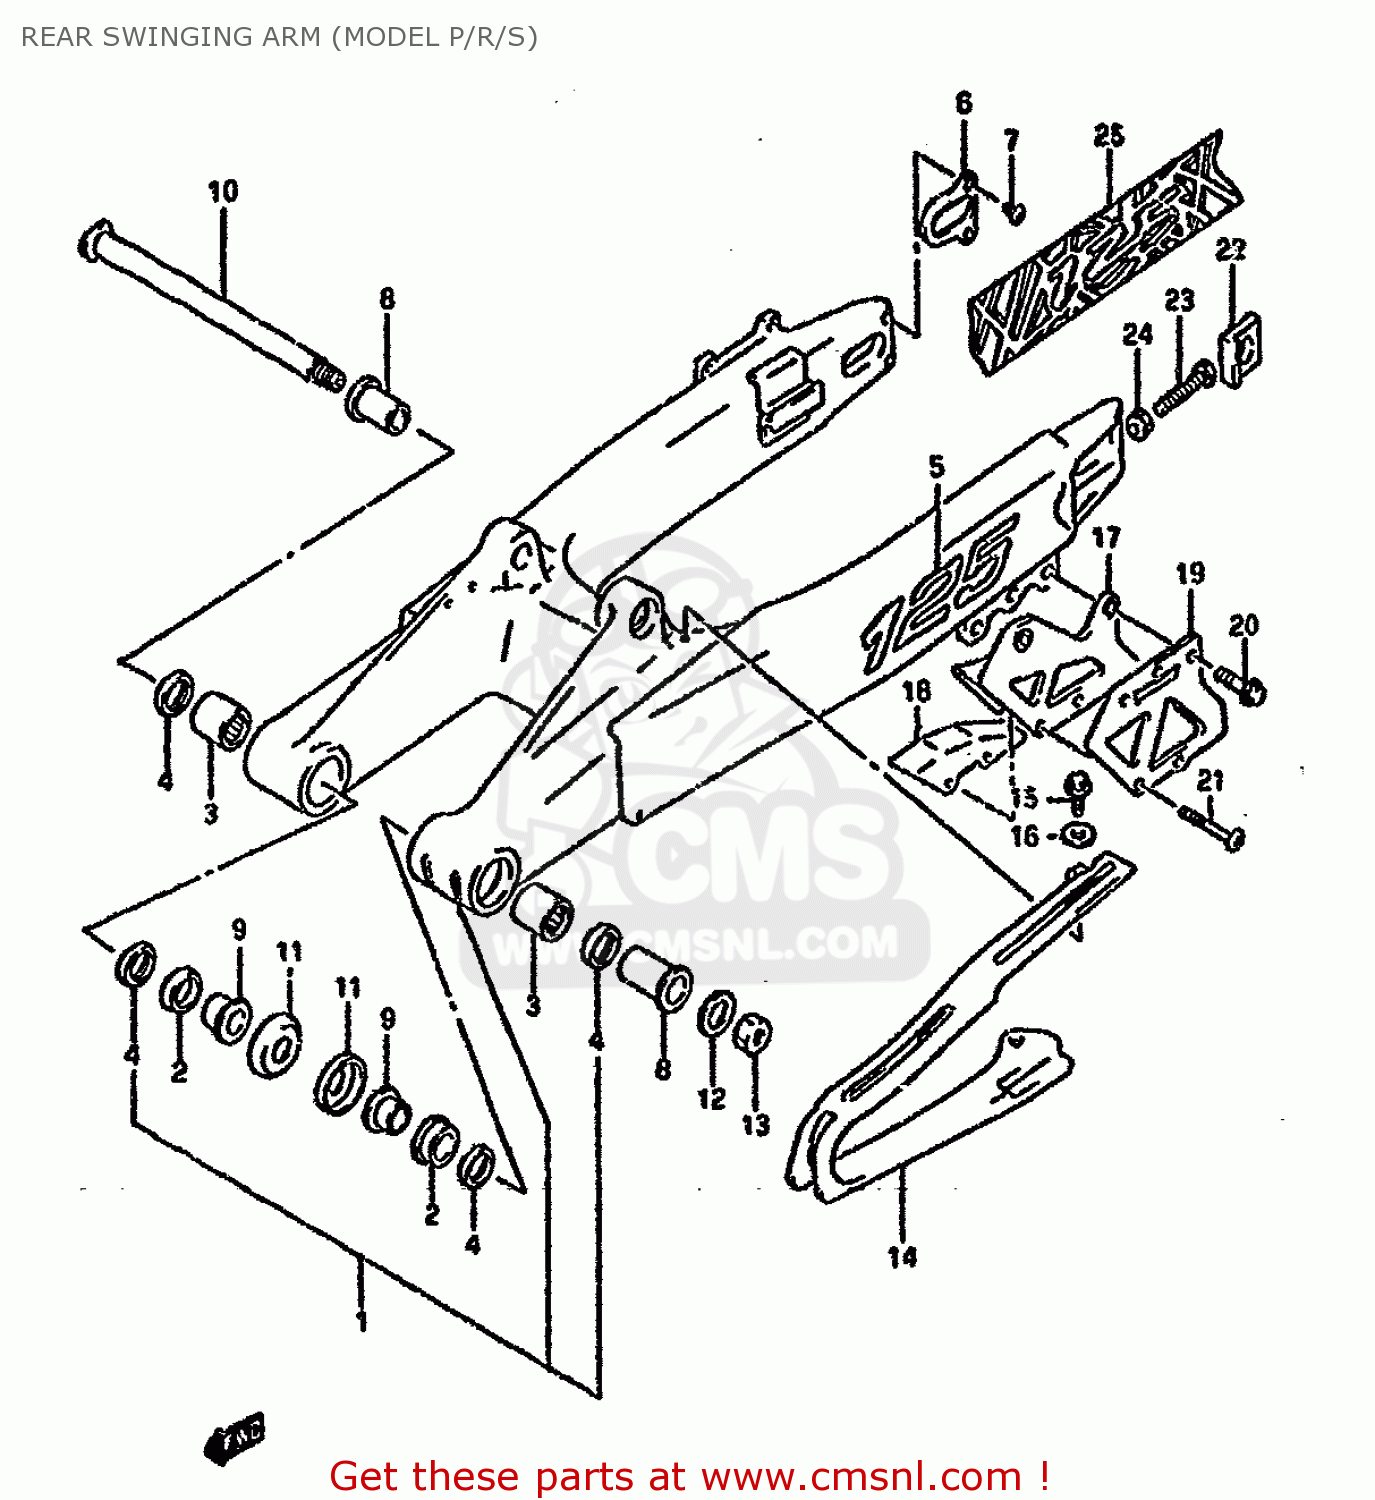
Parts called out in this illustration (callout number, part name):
1	SWING ARM ASSEMBLY,REAR
2	BUSHING,SWGARM PIVOT
3	BEARING(22X29X30)
4	SEAL,OIL(22X29X4)
5	EMBLEM,SWING ARM
6	PLATE,SWING ARM,REAR
7	SCREW(5X8)
8	SPACER,REAR SWING ARM
9	SPACER,SWGARM PIVOT INNER
10	SHAFT,RR SWINGINGARM PIVOT
11	COVER,SWINGINGARM PIVOT
12	WASHER
13	NUT
14	BUFFER,CHAIN TOUCH DEFENSE
15	BOLT
16	WASHER
17	GUIDE,CHAIN
18	DEFENSE,CHAIN GUIDE
19	PLATE,CHAIN GUIDE OUTER
20	BOLT
21	SCREW(6X40)
22	WASHER,CHAIN ADJUSTER
23	BOLT(8X50)
24	NUT
25	EMBLEM,SWING ARM
